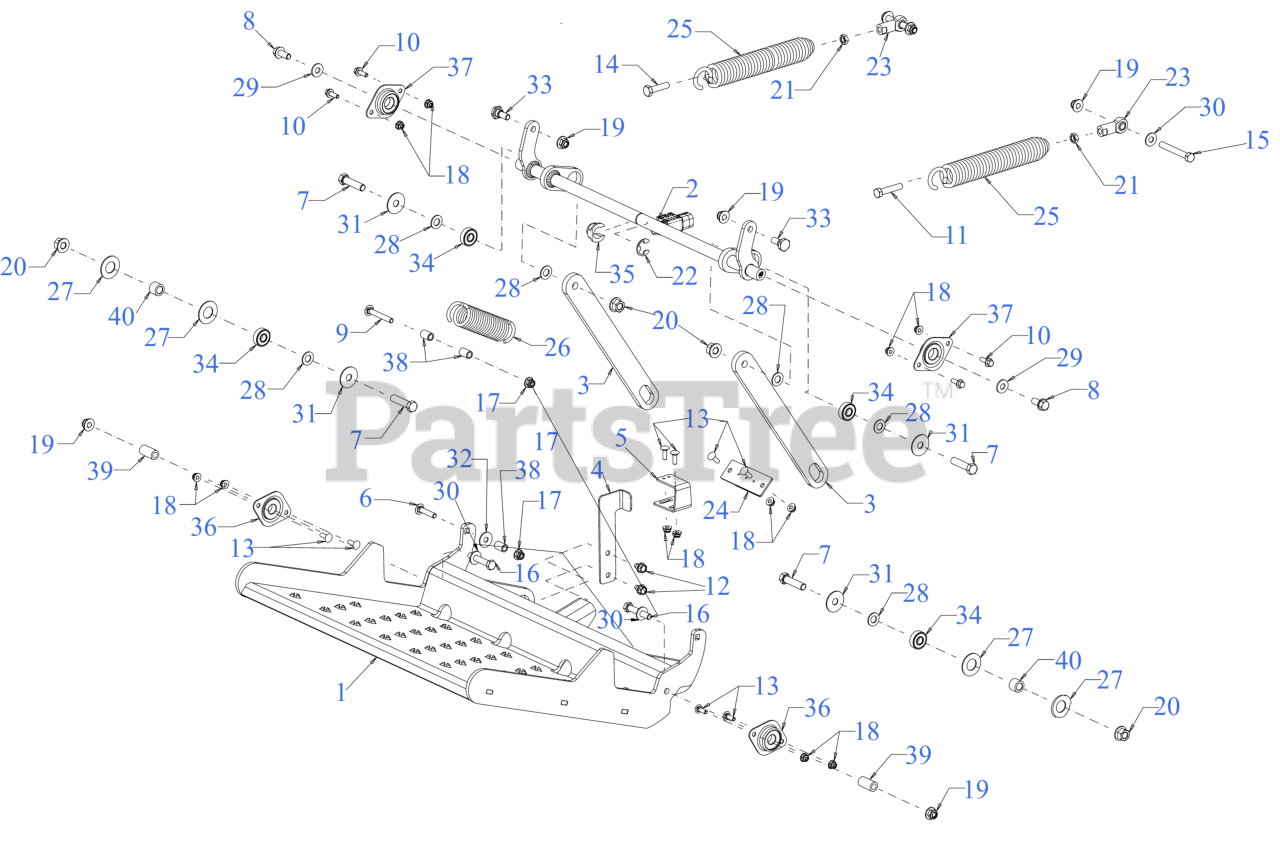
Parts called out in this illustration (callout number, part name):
1	PLATFORM ASSEMBLY
2	ROLLER LINK
3	SUSPENSION LINK
4	SWITCH BRACKET
5	OPC MOUNT BRACKET
6	CARRIAGE BOLT 5/16-18 x 1.50
7	SCREW 7/16-20 x 1.75 GR 5
8	SCREW 3/8-16 x .875 GR5
9	BOLT 5/16-18 x 2.50 GR1
10	SCREW 1/4-20 x .75 GR5
11	SCREW 3/8-24 x 1.75 GR5
12	SCREW 5/16-18 x .500
13	SCREW 1/4-20 x .75 GR5
14	SCREW 3/8-24 x 1.50 GR8
15	SCREW 3/8-16 x 2.75 GR5
16	SCREW 3/8-16 x 2.0 GR 8
17	FLANGE LOCK NUT 5/16-18
18	FLANGE LOCK NUT
20	FLANGE LOCK NUT
21	HEX JAM NUT 3/8X24
22	E-RING
23	ROD END 3/8 ID
24	SUSPENSION BUMPER
25	ADJUSTMENT SPRING
26	EXTENSION SPRING 1.478 x 5.729
27	FLAT WASHER .760ID X1.49OD x .06
28	FLAT WASHER
29	FLAT WASHER .385X.870X.090
30	FLAT WASHER
31	FLAT WASHER
32	FLAT WASHER 344X1.00
33	SHOULDER SCREW
34	BALL BEARING
35	HEX FLANGE SPLIT BEARING
36	BALL BEARING
37	BALL BEARING
38	SLEEVE .33X.50X.75 LG
39	SPACER .380x.624x1.040
40	SPACER .465x.760x.550
